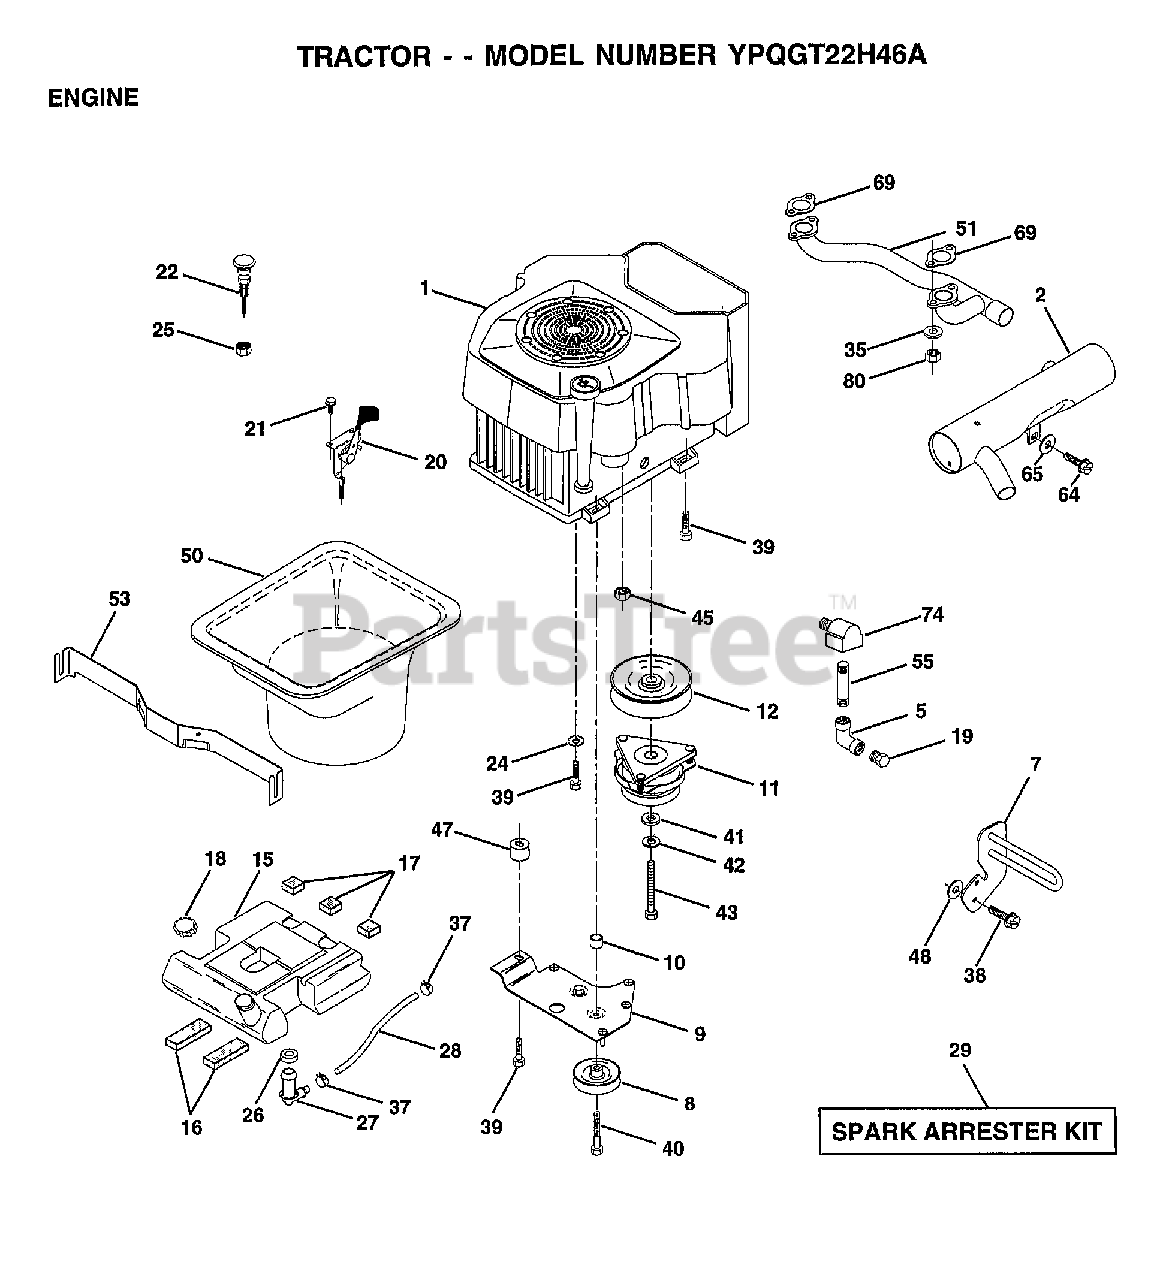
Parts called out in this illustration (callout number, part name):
2	MUFFLER.SIDE.VGT
5	ELBOW
7	GUARD.MUFFLER.ASM
9	KEEPER ASM BELT
10	BUSHING.
12	PULLEY.ENG.CLUTCH
15	TANK FUEL REAR
16	PAD IDLER TI
17	PAD-SPACER LT
18	CAP ASM FUEL
19	PLUG T
20	CONTROL.TRTL.37
21	SCREW LT
22	CHOKE CONTROL
24	LOCKWASHER
25	"NUT,KEPS 3/8-24IM"
26	BUSHING OUTLET T
27	STEM.TANK.FUEL
29	SPARK ARREST KIT
35	WASHER.SPLIT
37	HOSE CLAMP
38	SCREW
39	SCREW.3/8-16X2.25
40	SCREW.TT.3/8-16X4
41	WASHER
42	LOCKWASHER
43	BOLT.7/16-20X4.25
45	NUT
47	SPACER.ENGINE
48	WASHER T
50	DUCT AIR INTAKE
51	MANIFOLD.PIPE.VGT
53	ROD SUPT HOOD DUC
55	PIPE NIPPLE LT
64	SCREW
65	WASHER
69	GASKET
74	ELBOW STREET BASS
80	NUT FLANGE M8-125
